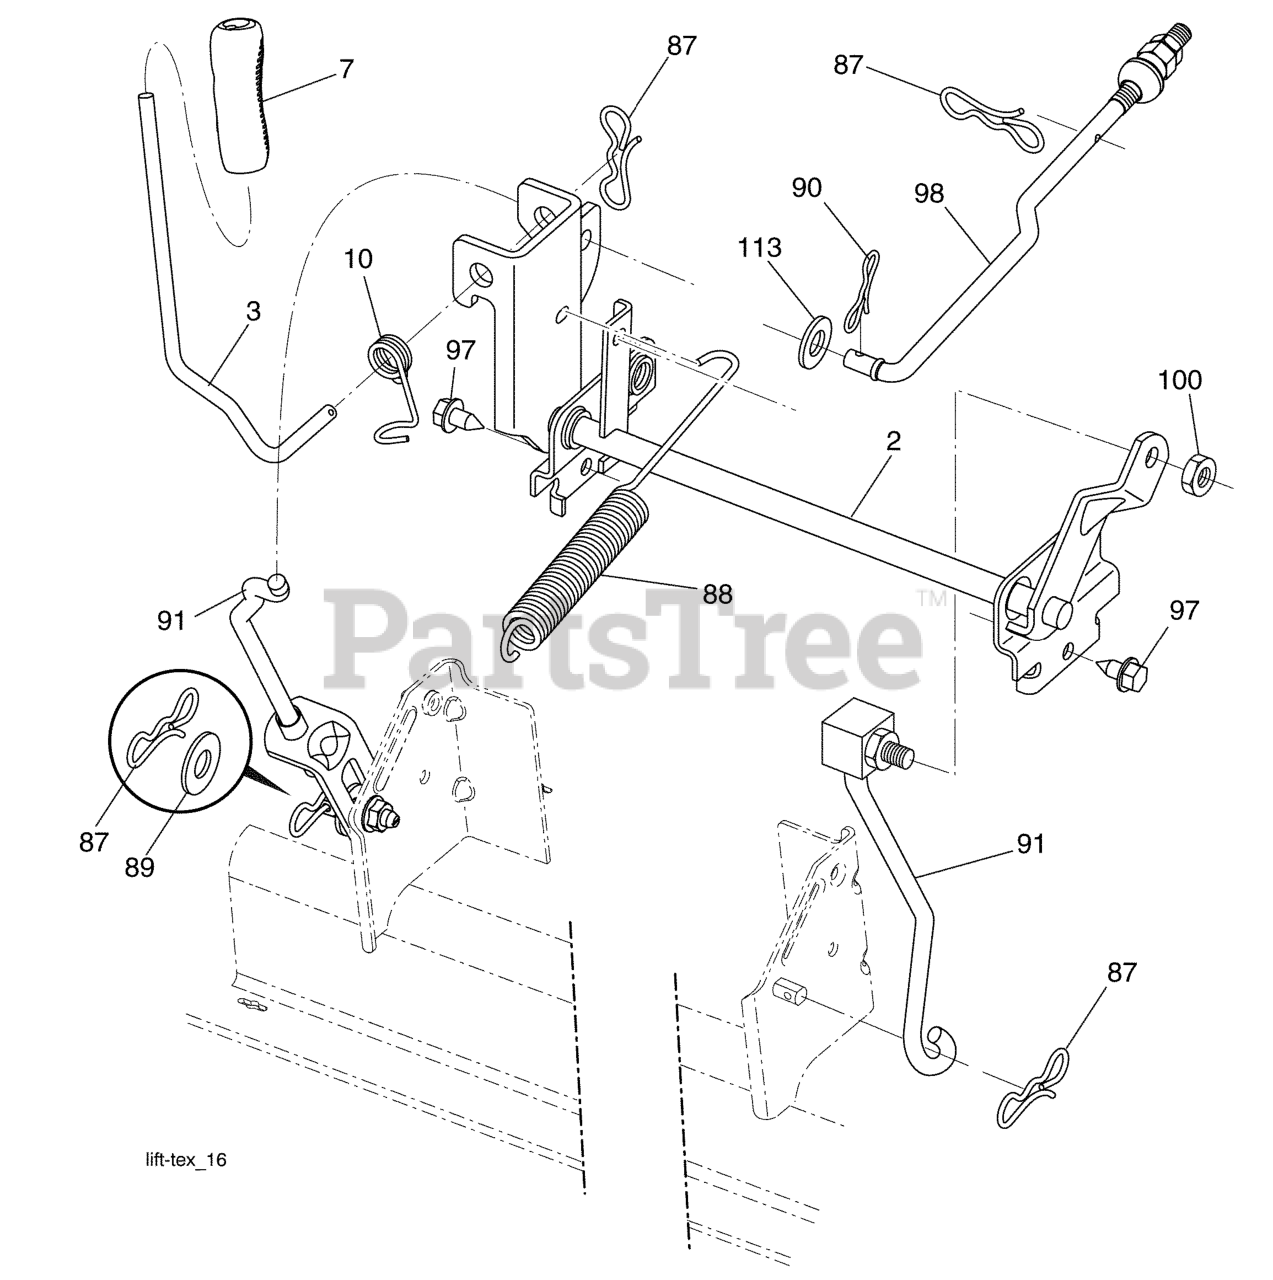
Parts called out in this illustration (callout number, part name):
2	SHAFT.ASM.LIFT.CROSS.H
3	LEVER.LIFT.HANDLE.GT
7	GRIP.HANDLE.LIFT.PVC.BLACK
10	SPRING.TORSION.LIFT.HANDLE
87	PIN.COTTER.7/16.BOW TI.
88	SPRING.LIFT.ASSIST
89	WASHER.CLEAR.ZINC
90	PIN.COTTER.5/16.BOW TI
91	LINK.ASM.LIFT.REAR
97	SCREW, 3/8-16X3/4
98	LINK.ASM.SUSP.FRONT.MW
100	LOCKNUT
113	Washer 17/32 x1-3/16 x 12 Ga.
